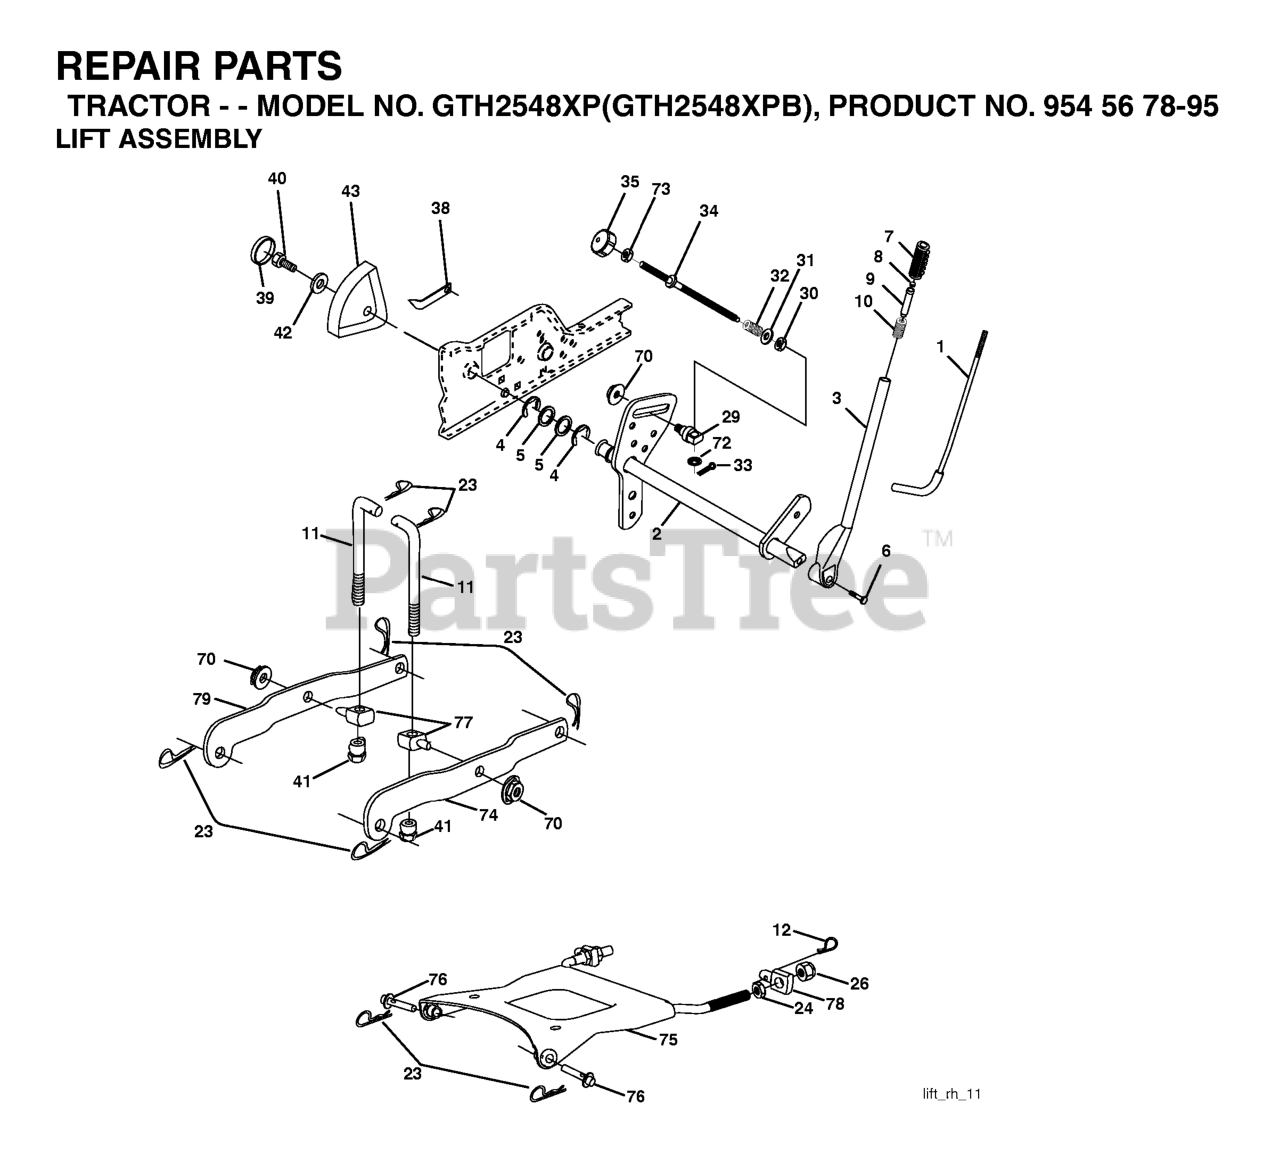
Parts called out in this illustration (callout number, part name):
1	LEVER ROD LT
2	SHAFT ASM., LIFT VGT
3	LEVER ASSY-LIFT RH
5	Washer 29/32 x 1 - 1/4 x 16 Ga.
6	Bolt, Fin Hex 3/8-16 x 1-1/12
7	GRIP HANDLE
8	PLUNGER BUT KIT
9	PLUNGER BUT KIT
10	SPRING 0.620D X 2.125
11	LIFT LINK
12	SPRING RETAINER
23	RETAINER-SPRNG RB
24	NUT.HEX.JAM.1/2-13
26	NUT.LK.W/WSH.1/2.
32	SPRING.COMP.INF.H
33	COTTER PIN
34	ROD.LIFT.ADJUSTABLE
35	KNOB INF 3/8-16
38	POINTER, HEIGHT INDICATOR(2 2)
40	SCREW 5/16-18X1
41	NUT, LIFT LINK 7/16-20
43	HEIGHT INDICATOR
70	NUT
72	NUT PUSH M
73	NUT
74	ARM SUSP REAR RH
75	PLATE ASM SUSP FRONT
76	PIN.FLANGE
79	ARM SUSP. REAR LH
